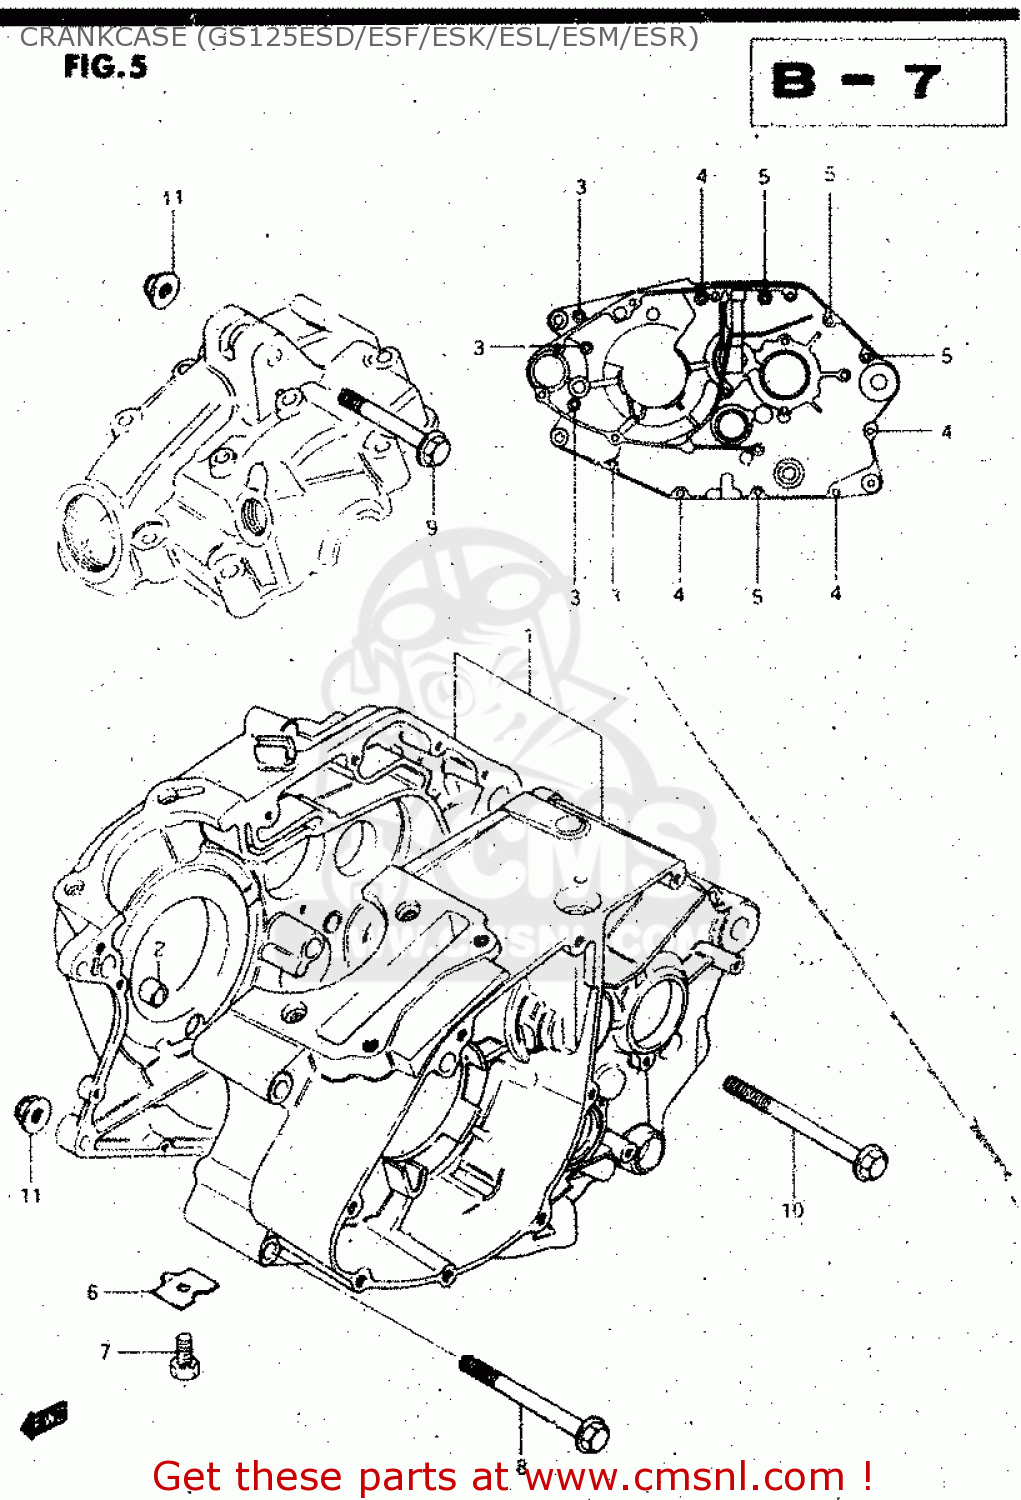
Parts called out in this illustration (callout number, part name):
1	CRANKCASE SET
2	PIN
3	BOLT
4	BOLT
5	BOLT
6	PLATE,OIL GALLERY PLUG
7	BOLT
8	BOLT(8X80)
9	BOLT(8X50)
10	BOLT(8X88)
11	NUT
